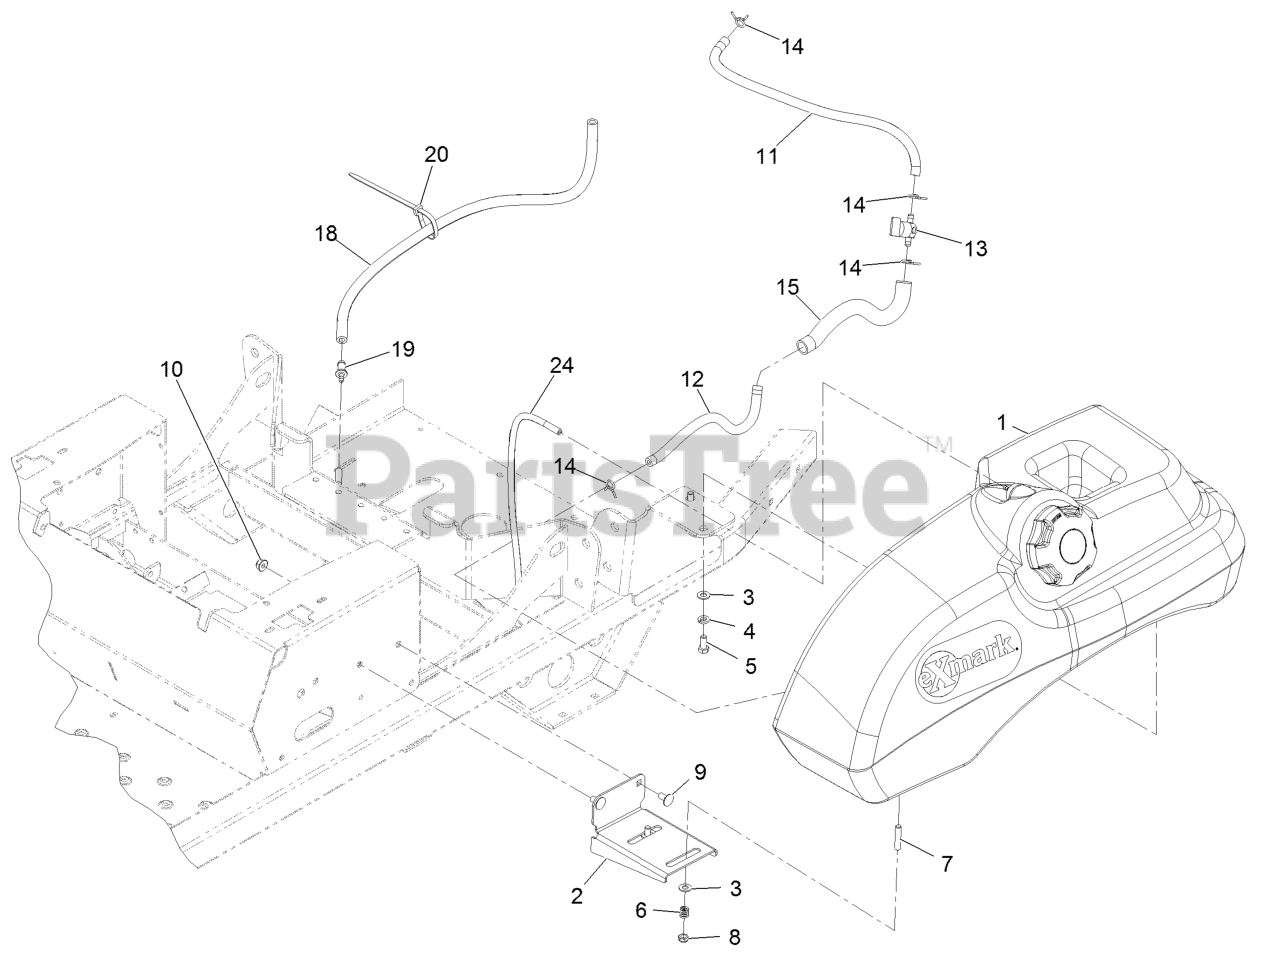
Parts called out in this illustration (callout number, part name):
1	ASM-FUEL TANK
2	BRACKET-TANK AND FENDER
3	WASHER-PLAIN
4	WASHER-LOCK
5	SCREW-HH
6	SPRING-TANK, FUEL
7	STUD
8	NUT-LOCK, NI
9	SCREW-CARR
10	NUT-HF, NI
11	HOSE-FUEL
12	HOSE-FUEL
13	VALVE-FUEL
15	CONDUIT-FUEL LINE
18	HOSE-FUEL
19	FITTING-ORIFICE, STRAIGHT
20	TIE-PLASTIC
24	HOSE,EMISSIONS
